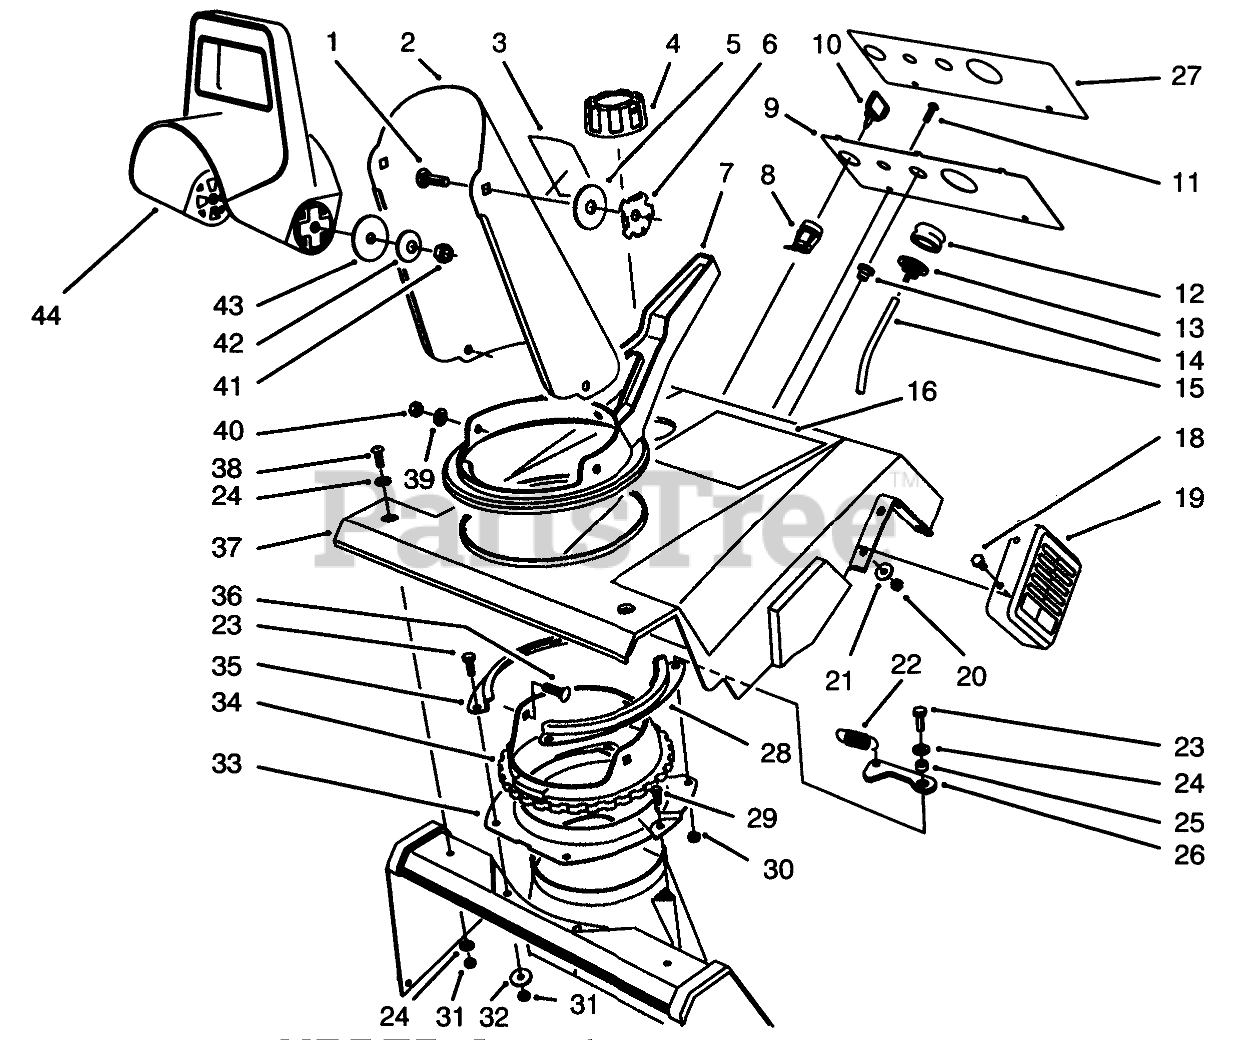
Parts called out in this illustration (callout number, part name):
1	SCREW-CARR
2	Discharge Chute Assembly (Incl. Ref. #3)
3	DECAL-DANGER
4	CAP-FUEL ASM
5	WASHER-RUBBER
6	PLATE-FRICTION
7	CHUTE - HANDLE
8	SWITCH
9	Panel-Control
9	Panel-Control (Model 38196)
10	KEY-IGNITION
11	SCREW-SHWH, THREAD FORMING
12	BULB-PRIMER
13	BODY-PRIMER
14	GUIDE-ROPE, STARTER
15	HOSE-PRIMER
16	DECAL - CCR 1000E
18	SCREW-HWH
19	Guard-Muffler
20	NUT-LOCK, NI
21	WASHER-FLAT
22	SPRING-EXTENSION
23	SCREW-HH
24	WASHER-FLAT
25	SPACER-BLADE, ROTOR
26	DETENT
27	DECAL - CONTROL PANEL
28	Retainer-Chute Ring
29	SCREW-PLASTITE
30	NUT-LOCK, NI
31	NUT-LOCK, NI
32	WASHER-FLAT
33	Ring-Chute Support
34	Ring-Chute (Model No. 38191 Only)
35	Retainer-Chute Ring
36	SCREW-CARR
37	SHROUD-UPPER
38	SCREW-PPH
39	WASHER-FLAT
40	NUT-KEPS
41	NUT-LOCK, NI
42	WASHER-BELLEVILLE
43	WASHER-FLAT
44	CHUTE-DEFLECTOR
